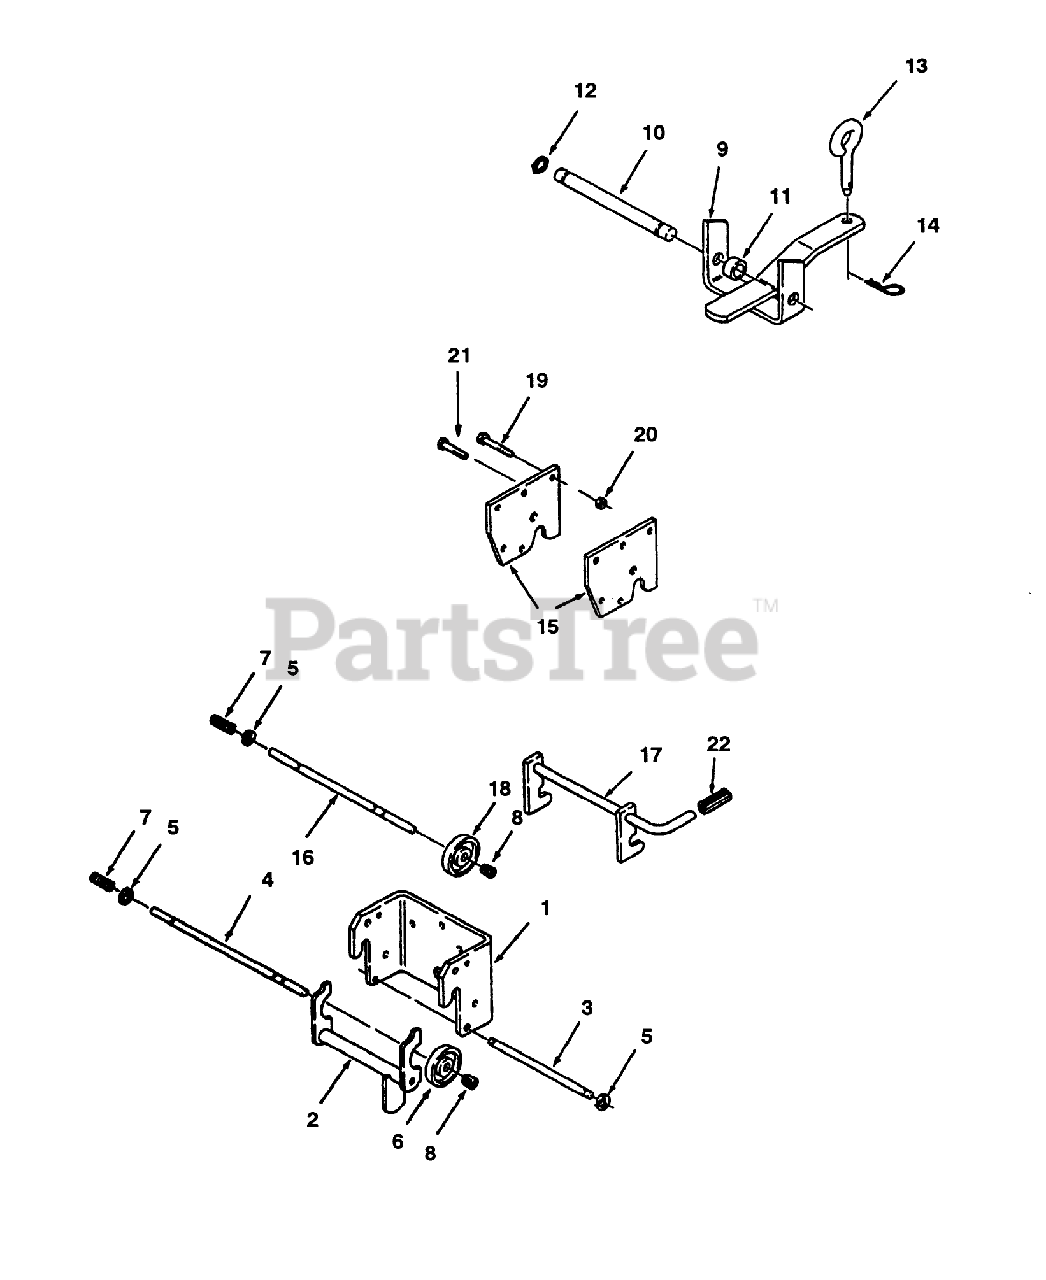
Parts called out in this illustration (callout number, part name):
3	ROD-LATCH PIVOT
4	ROD-LOCK
5	RING-RETAINING
7	SPRING
8	CAP-ROD, PLUNGER
10	PIN-STATIONARY HITCH
12	E-RING
13	PIN-TOOL
14	Hairpin Cotter
17	MID HITCH ASM
18	ROD-LOCK
19	SCREW-HH
20	NUT-LOCK, NI
21	SCREW-HH
22	GRIP
